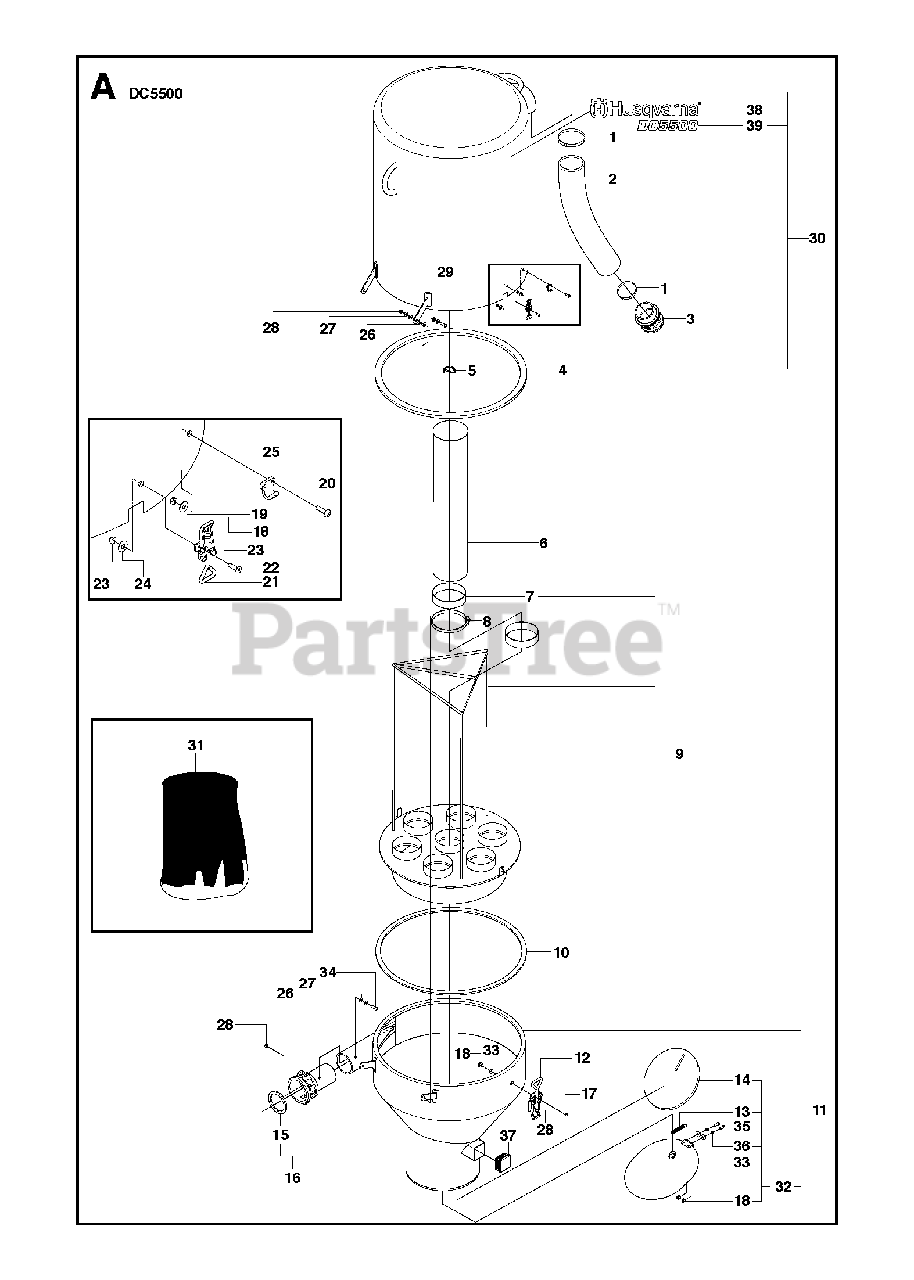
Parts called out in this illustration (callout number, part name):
17	SCREW CRCSFM
18	HEXAGON LOCKING NUT
23	HEXAGON LOCKING NUT
27	WASHER
28	HEXAGON LOCKING NUT
31	BAGSINCLUDES 200 ITEMS
